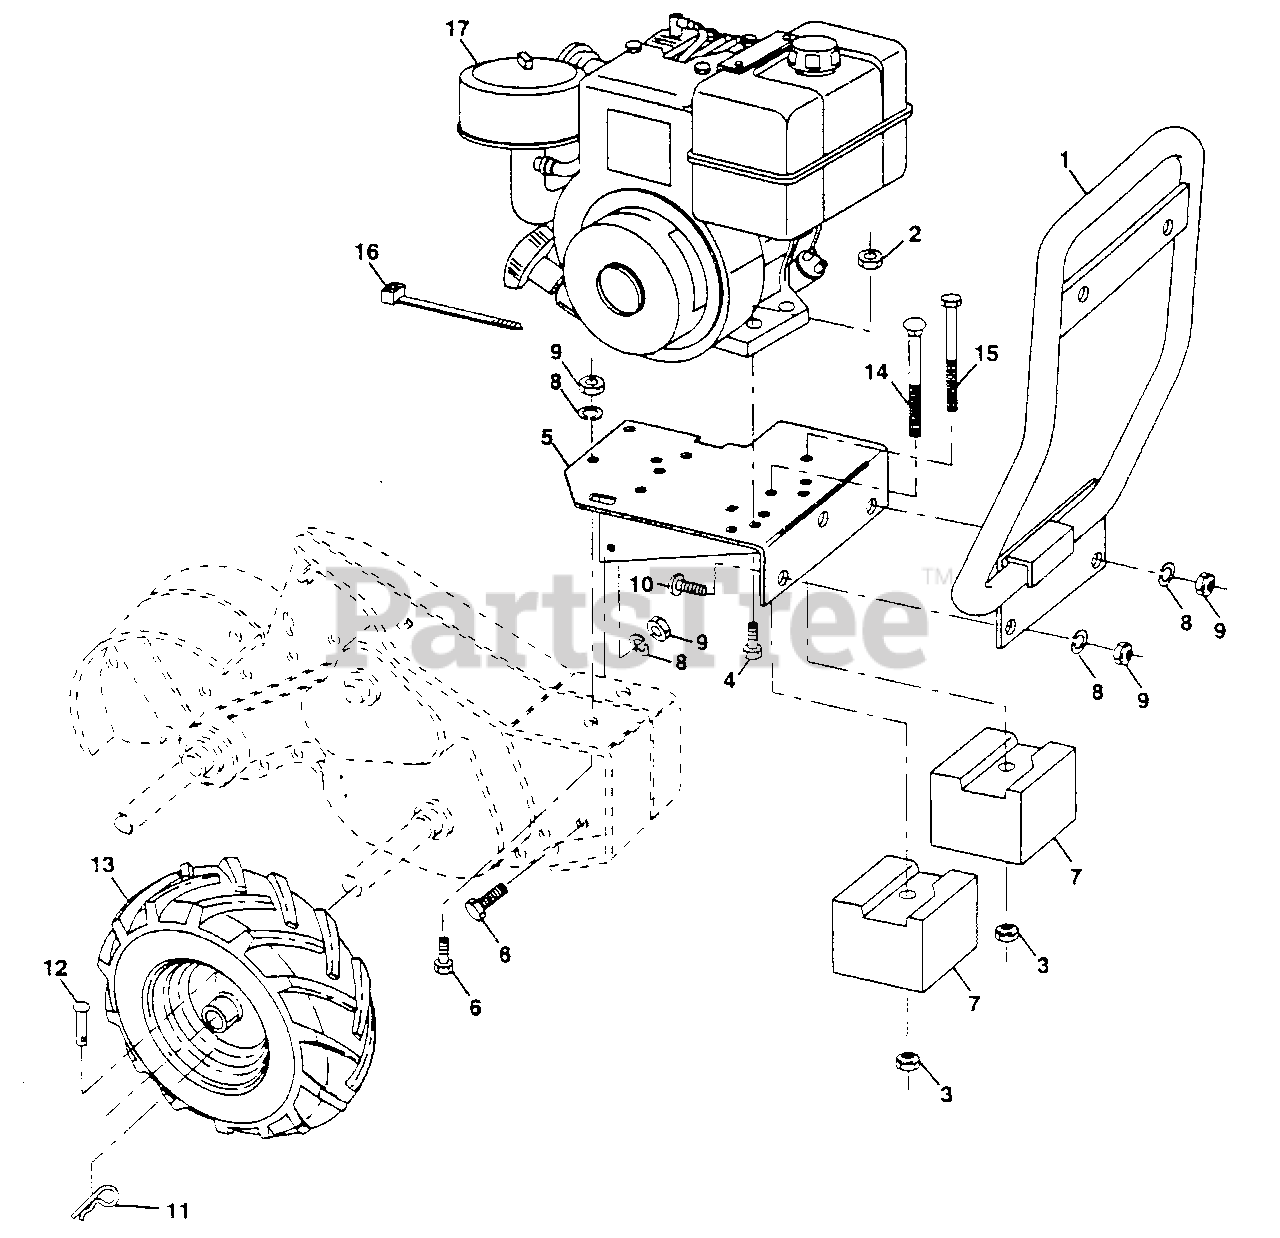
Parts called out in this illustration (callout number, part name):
1	Bumper (AYP part number)
2	Nut, Crownlock 5/16-18
3	Nut, Crownlock 3/8-16
4	Bolt, Hex 5/16-18 x 1-3/4 (AYP part number)
5	Bracket, Engine (AYP part number)
6	Bolt, Hex Head 3/8-16 x 1 (AYP part number)
7	Counter Weight, R.H. (AYP part number)
8	Washer, Lock 3/8 (AYP part number)
9	Nut, Hex 3/8-16 (AYP part number)
10	Bolt, Carriage 3/8-16 x 1 (AYP part number)
11	Clip, Hairpin (AYP part number)
12	Rivet, Drilled
13	Tire (AYP part number)
14	Bolt, Carriage 3/8-16 x 4-1/2 (AYP part number)
15	Bolt, Hex Head 3/8-16 x 4-1/2 (AYP part number)
16	Tie, Cable (AYP part number)
